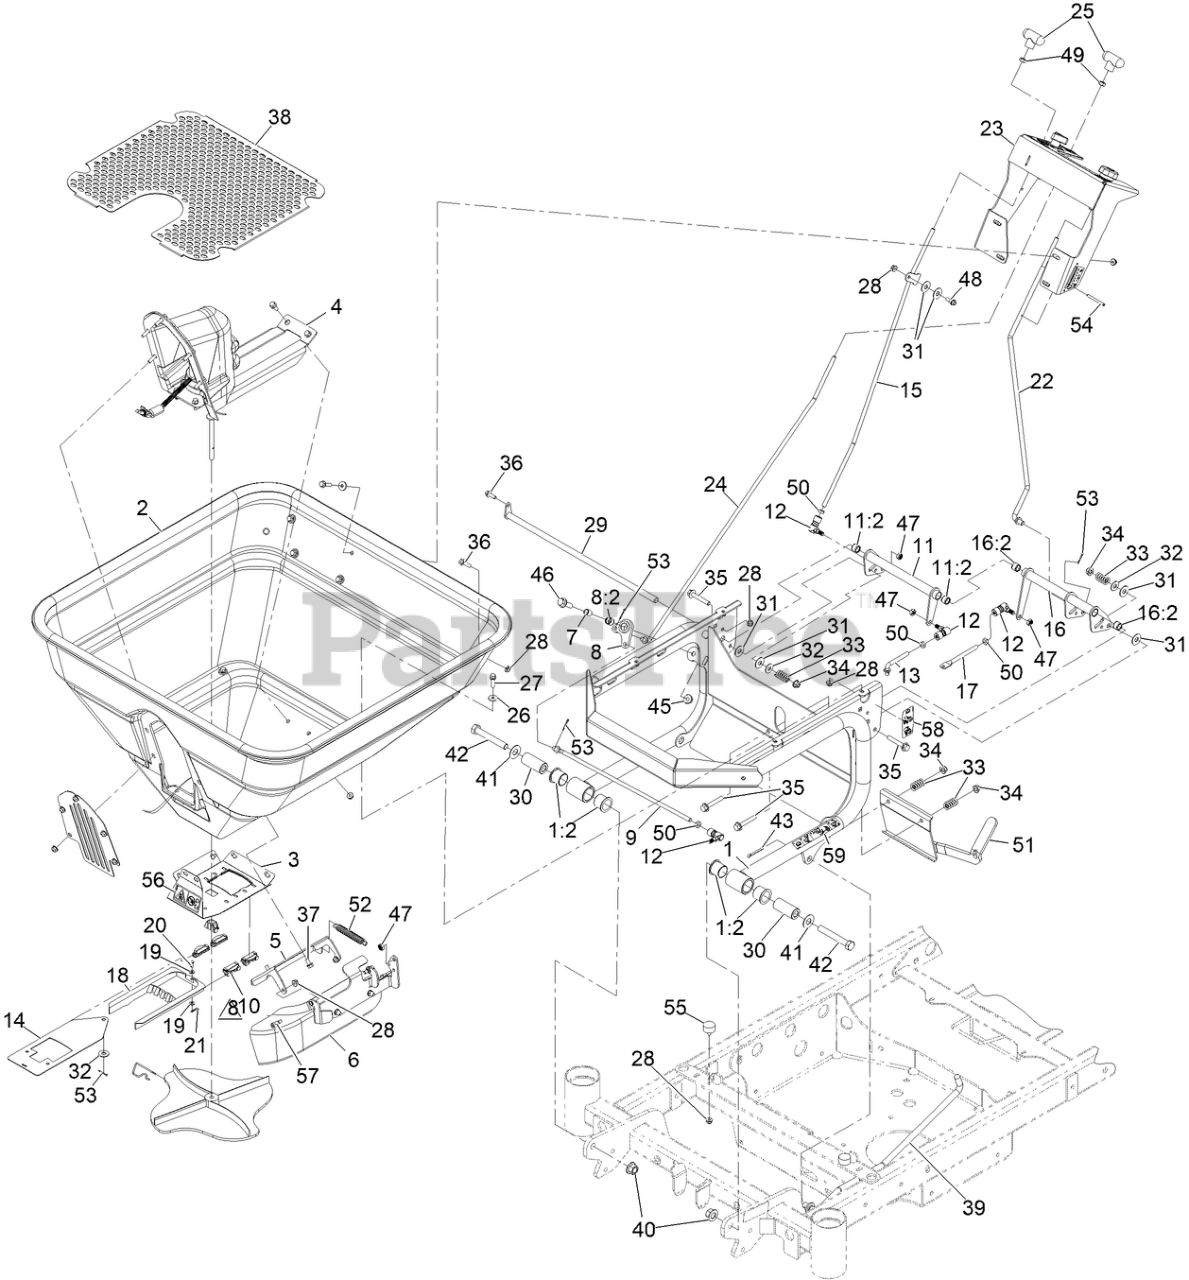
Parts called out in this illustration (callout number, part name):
1	FRAME-HOPPER
1:2	BUSHING-PIVOT
2	HOPPER-250 LB.
3	PLATE-HOPPER, BOTTOM
4	ASM-Motor, Hopper
5	BRACKET-HOPPER DEFLECTOR
6	ASM-Deflector, Side
7	BUSHING-PIVOT, DEFLECTOR
8	CRANK-DEFELCTOR
8:2	BUSHING
9	LINKAGE-DEFLECTOR, LOWER
10	GUIDE-RATE, GATE
11	CRANK-GATE, HOPPER
11:2	BUSHING
12	Ball Joint-Quick Disconnect, SS
13	LINKAGE-GATE, LOWER
14	RATE-GATE
15	LINKAGE-GATE, UPPER
16	CRANK-DIFFUSER
16:2	BUSHING
17	LINKAGE-DIFFUSER, LOWER
18	DIFFUSER
19	WASHER-FLAT
20	PIN-CLEVIS
21	PIN-COTTER, HAIR
22	LINKAGE-DIFFUSER, UPPER
23	ASM-Console, Hopper
24	LINKAGE-DEFLECTOR, UPPER
27	SCREW-HHF
28	Nut-Hex Flange
29	SHAFT-CONTROL, HOPPER
30	SPACER-PIVOT, HOPPER
32	FLAT WASHER, 5/16 NOM,ST
33	SPRING-COMPRESSION
34	Nut-Hex Flange
35	SCREW-HHF
36	Screw-HHF
37	SCREW-HWH
38	SCREEN-HOPPER, MEDIUM
39	ROD-PROP, HOPPER
40	NUT-HEX FLANGE
42	SCREW-HH
43	Pin-Cotter
45	Nut-Hex Flange
46	SCREW-HHF
47	NUT-LOCK, NI
48	BOLT-SHOULDER
49	NUT-HEX
50	Nut-Hex
51	LATCH-HOPPER
52	SPRING-EXTENSION
53	COTTER PIN 5/64X3/4 18-8
54	PIN-ROLL, 3/16 X 2.0
55	BUMPER-RUBBER
56	Decal-Dismemberment Hazard
57	BOLT-SHOULDER
58	DECAL-HOPPER ROTATE
59	DECAL-HOPPER LATCH
